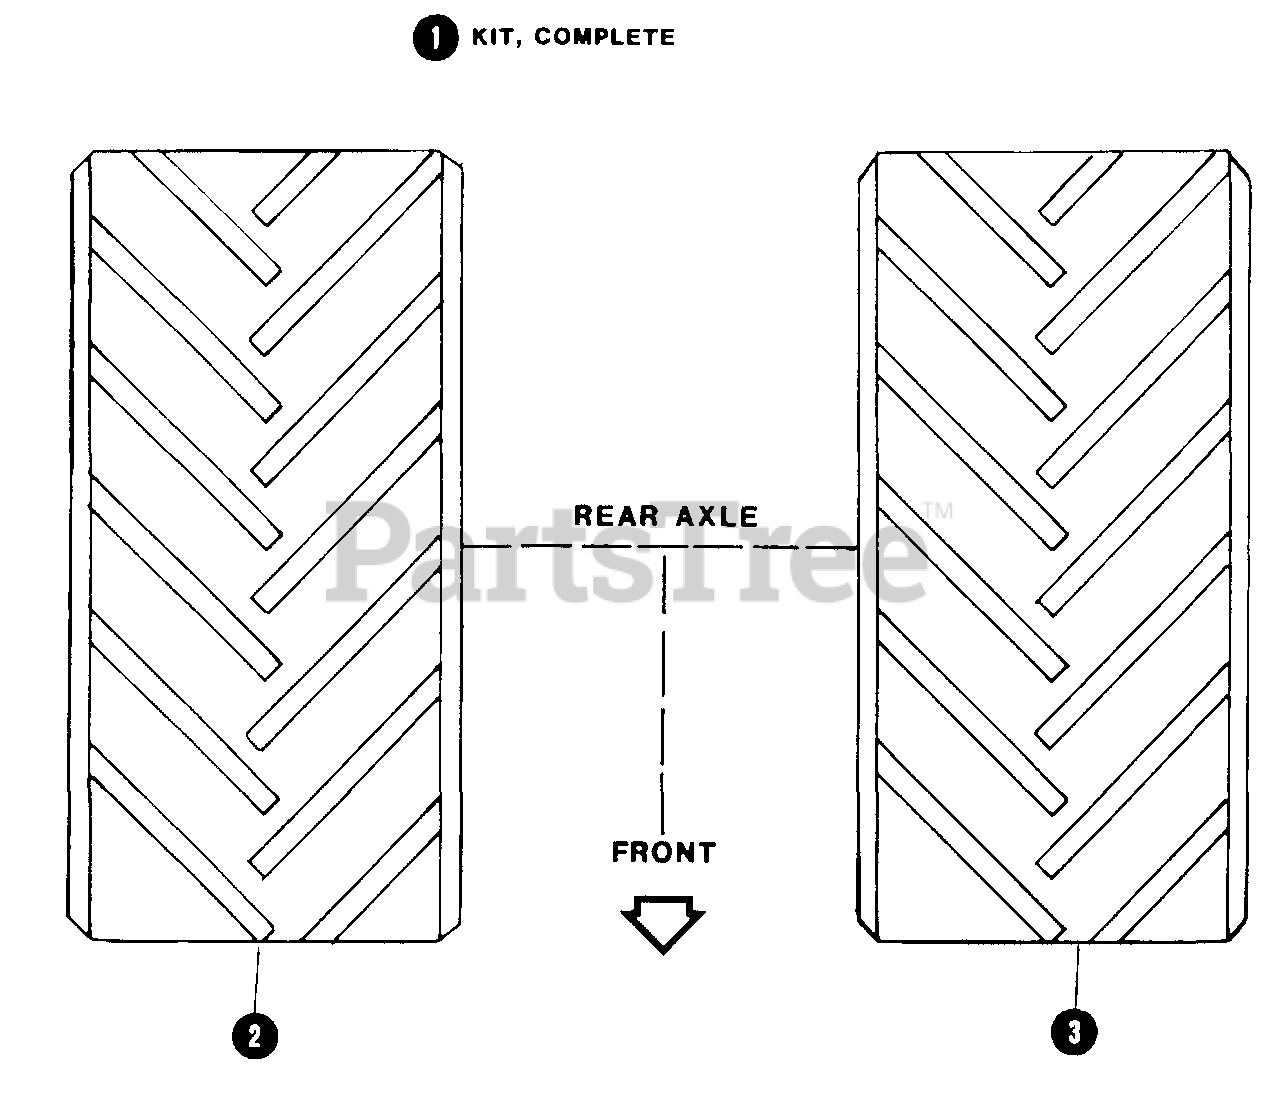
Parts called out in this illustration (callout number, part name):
1	KIT, AG REAR TIRE
2	WHEEL & TIRE ASSEMBLY - RIGHT SIDE
3	WHEEL & TIRE ASSEMBLY - LEFT SIDE
